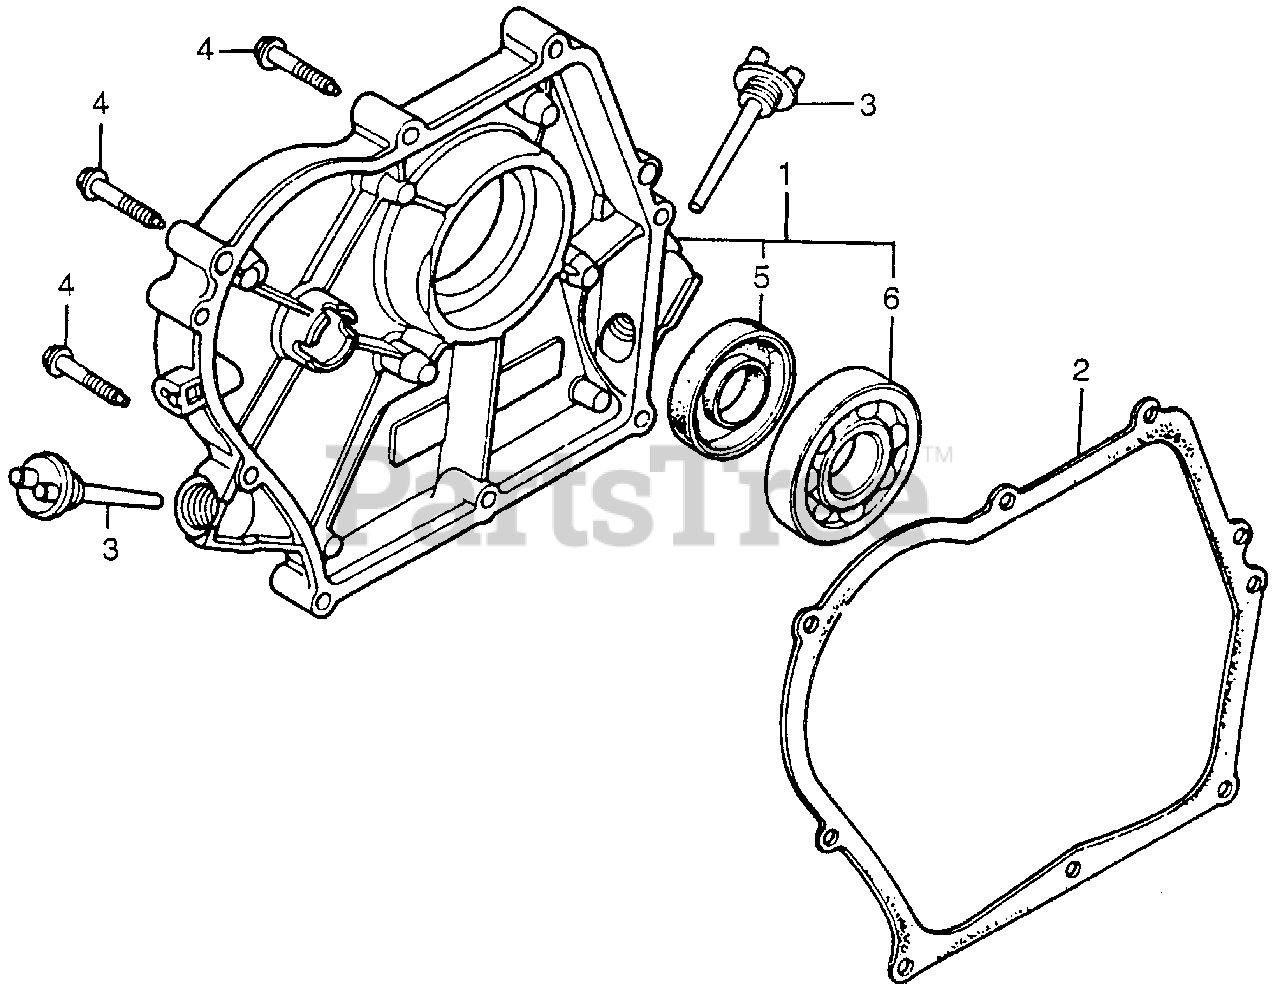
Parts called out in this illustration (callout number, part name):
1	COVER ASSY., CRANKCASE (S-TYPE)
2	GASKET, COVER
4	BOLT, FLANGE (6X32)
5	OIL SEAL (25X41X6)
6	BEARING, RADIAL BALL (6205)
